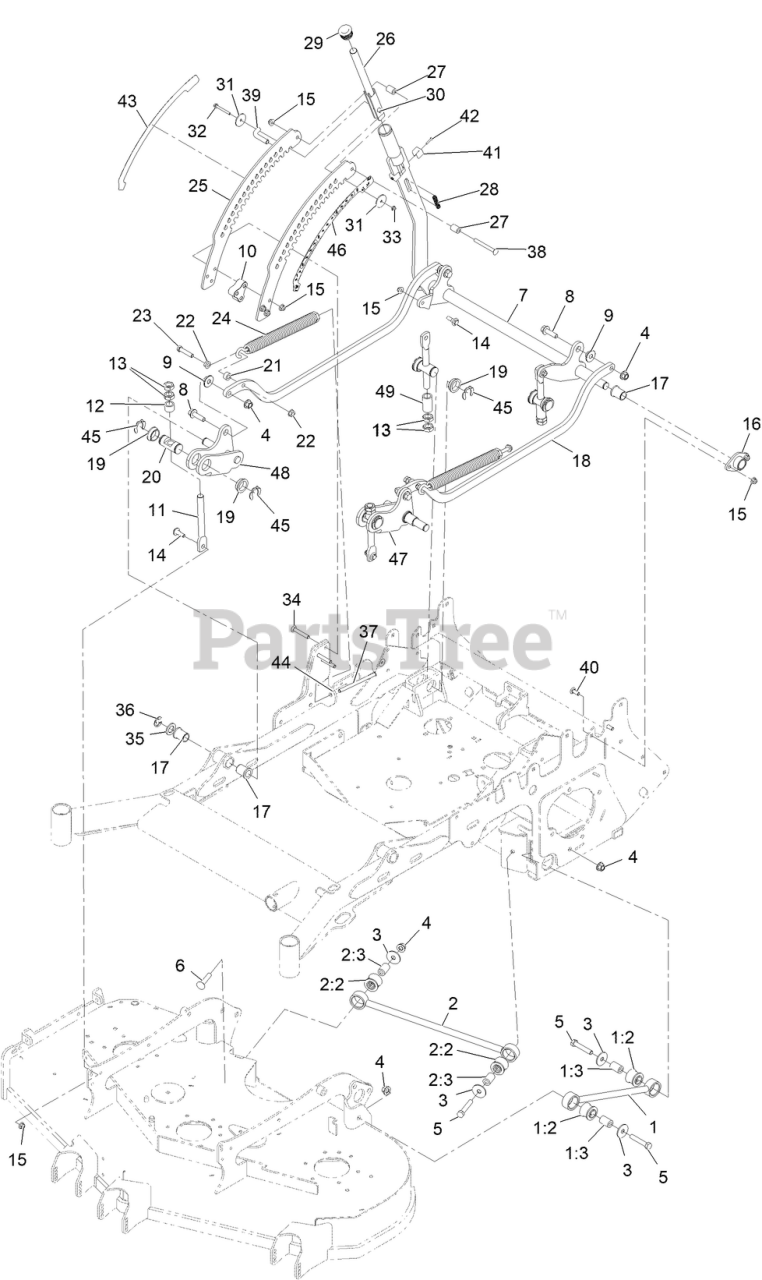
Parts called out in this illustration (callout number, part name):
1	ASM, DECK STRUT
1:2	BUSHING-RUBBER
2	PANHARD ROD ASM
2:2	BUSHING-SUSPENSION, RUBBER
3	WASHER-THRUST
4	Nut-Lock 1/2-13
5	SCREW-HH
6	SCREW-CARR
7	CROSS SHAFT -DECKLIFT-REAR
8	SCREW-HHF
10	SPACER-HOC VERTEX
11	LINK-DECKLIFT
12	SPACER-DECKLIFT
13	NUT-JAM
14	SCREW-SHOULDER, HHF
15	NUT-HF, NI
16	Support-HOC Shaft
17	BUSHING-FLANGED
18	LINK-HOC 52-60
19	BUSHING-FLANGED HOC
20	TRUNION-DECKLIFT GROOVED
23	SCREW-HH
24	SPRING-EXTENSION
25	PLATE-HOC
26	ASM-PLUNGER-HOC
27	TUBE-INTERLOCK
29	PLUG-PLASTIC HOC
31	SPACER-HOC
32	SCREW-HHF
34	SCREW-CARR
36	RING-RETAINING, EXT
37	BOLT-TAP, HH
38	SCREW-CARR
39	PIN-HOC
40	SCREW-CARR
41	CHANNEL-HOC GUIDE
42	SCREW-SHWH
43	DECAL-HEIGHT OF CUT,OUTER
45	E-RING WIDE GRIP
46	DECAL-HEIGHT OF CUT-INNER
47	WELD-ARM-DECKLIFT-FRONT-LH
48	WELD-ARM-DECKLIFT-FRONT-RH
49	SPACER 1.13 O.D. X .81 I.D. X 2.05L
